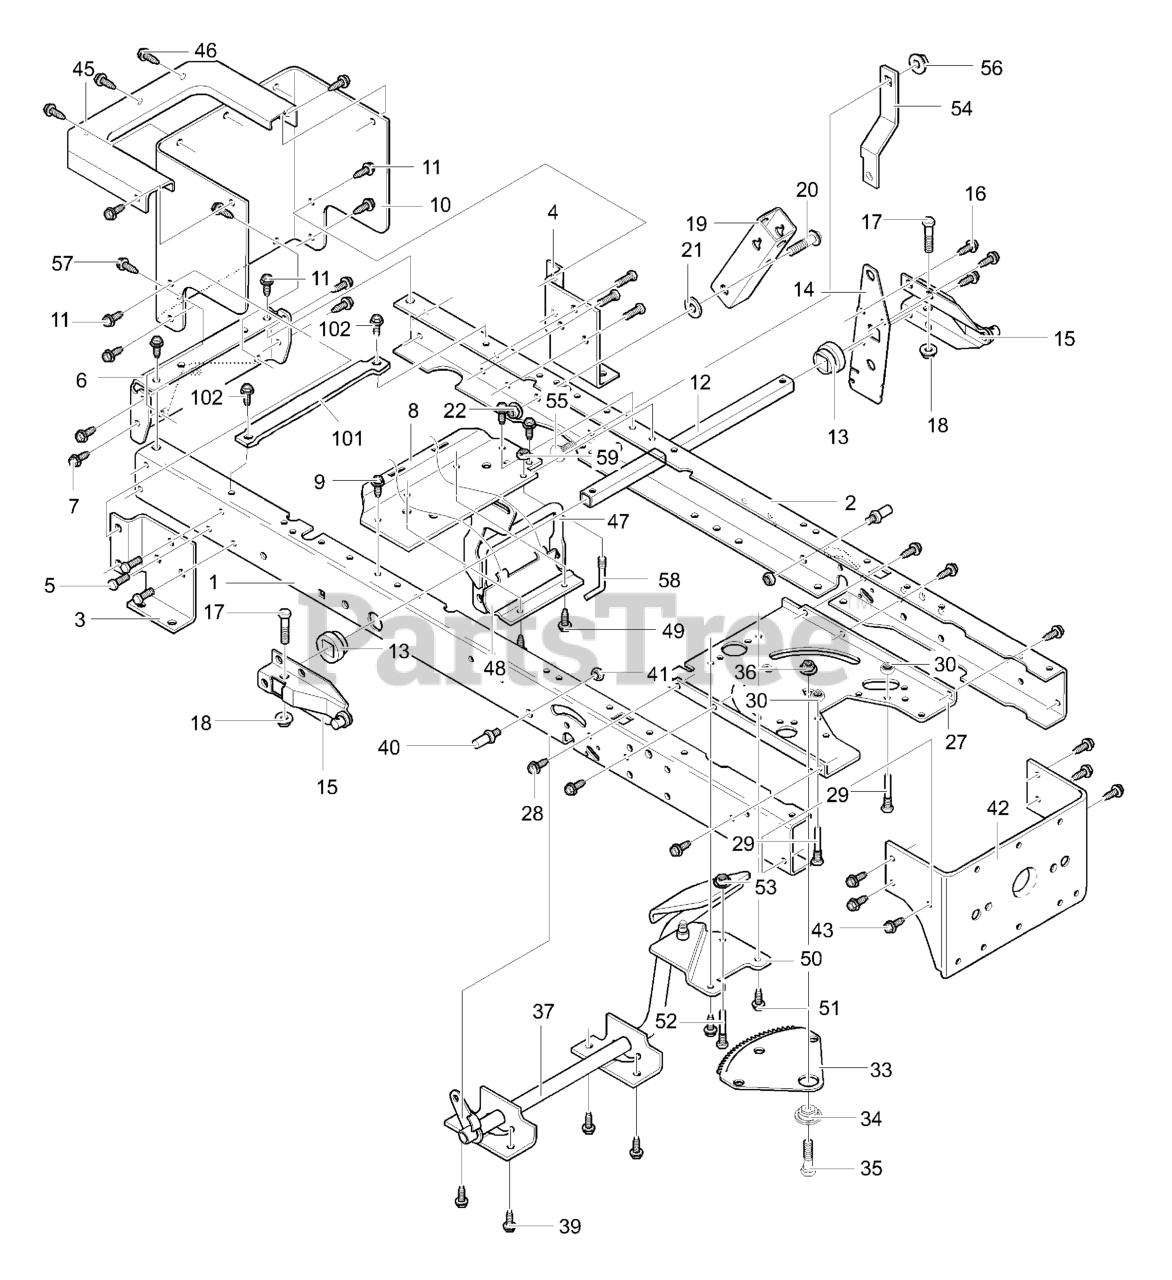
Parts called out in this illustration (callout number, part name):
1	RAIL-FRAME RH SHORT
2	RAIL-FRAME LH SHORT
3	BRACKET-TRANSAXLE RH
4	BRACKET-TRANSAXLE LH
5	SCREW-5/16-18X.75
7	SCREW-5/16-18X.75
8	BRACKET, IDLER
9	SCREW-5/16-18X.75
10	PLATE, REAR
11	SCREW-5/16-18X.75
12	TUBE, LIFTER
13	BUSHING - LIFT TUBE
14	PLATE-LIFT ARM
15	LIFT ARM LEVER
16	SCREW .31X50
17	SCREW, 5/16-24 x 1.25
18	NUT, FLANGELOCK
19	BRACKET, SQ TUBE PIVOT
21	WASHER, FLAT
22	NUT, FLNG CENTERLOCK
23	CRANK, PTO
24	BRACKET, BELL CRANK
25	SCREW-5/16-18X.75
26	WASHER, FLAT
27	PLATE, STEERING
28	SCREW-5/16-18X.75
29	ZINC SCREW GUIDE 5/16-18
30	NUT.32-18 FLANGELOCK
31	SCREW - GUIDE
32	BOLT
33	GEAR, SECTOR
34	BEARING, SECTOR GEAR
35	CAPSCREW, Hex Head, 5/16-18 x 1
36	NUT, 5/16
37	PEDAL
39	SCREW-5/16-18X.75
40	PIN,THREADED SHOULDER
41	NUT, 3/8-16
42	BRACKET, HANGER REAR
43	SCREW-5/16-18X.75
45	TOP, REAR PLATE
46	SCREW - THREAD FORM
47	YOKE ASSY-TRUNNION
48	CLAMP, TRUNNION PIVOT
49	SCREW-5/16-18X.75
50	IDLER INTERMEDIATE
51	SCREW, 5/16-18 x 0.50
52	SCREW GUIDE 5/16-18
53	NUT, FLANGELOCK
54	BRACKET, Torque Strap, LH
55	BOLT, CARRIAGE 31-18X0.62
56	NUT, CENTERLOCK
57	BOLT-3/8 X 1.25
58	SCREW - GUIDE
59	NUT, FLANGELOCK
101	BRKT, BATTERY SUPPORT
102	SCREW-5/16-18X.75
